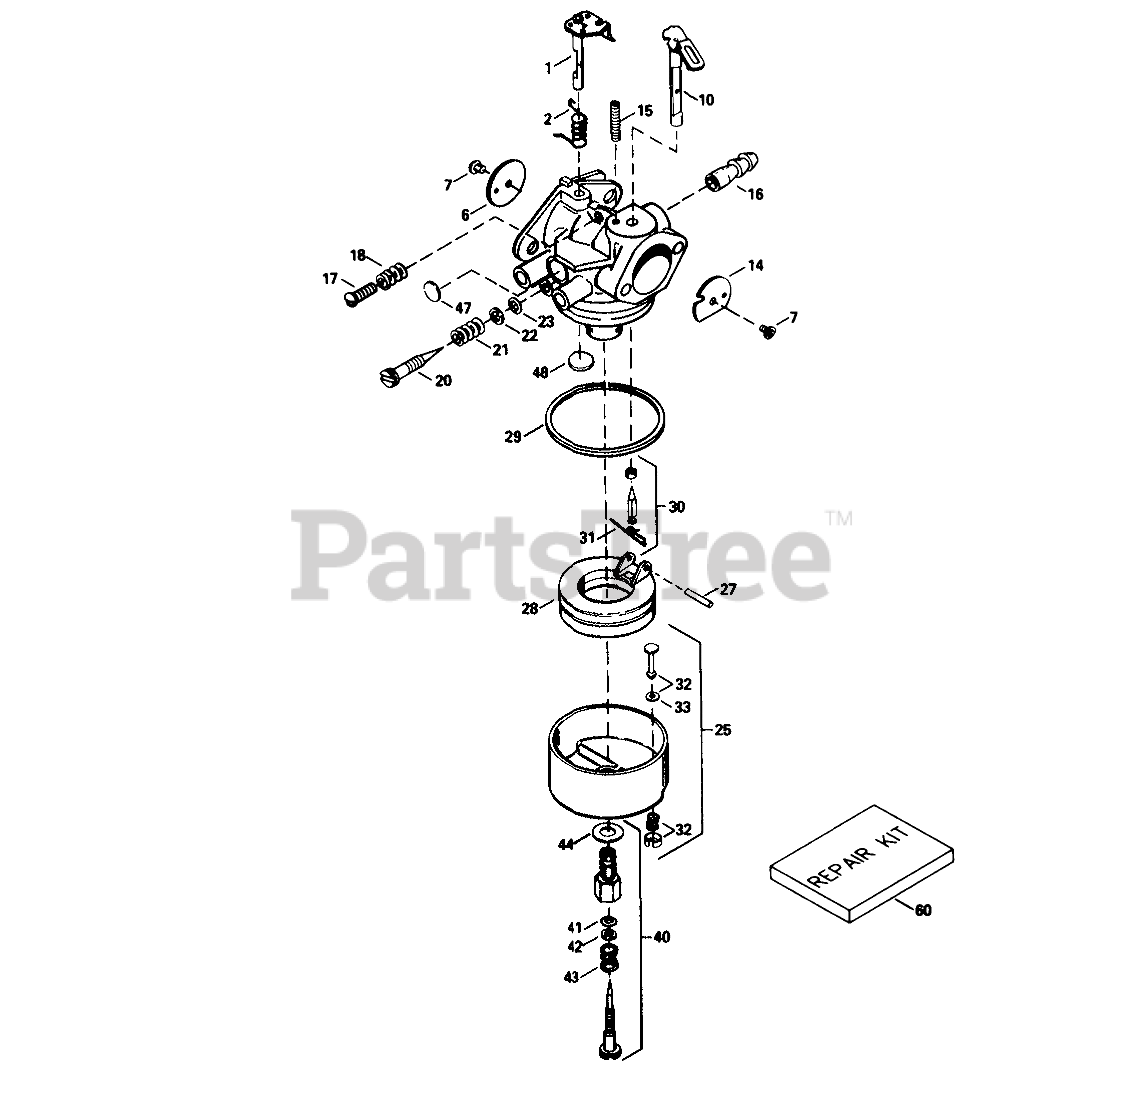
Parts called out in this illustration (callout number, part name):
1	Throttle Shaft and Lever ASM
2	Spring-Return, Throttle
6	Shutter-Throttle
7	Screw-Shutter
10	Choke Shaft and Lever ASM
14	Shutter-Choke
15	Spring-Positioning, Choke
16	Fitting-Fuel
17	Screw-Throttle Crack Screw / Idle Speed
18	Spring-Tension
20	Screw-Idle Mix
21	Spring-Tension
23	"O"Ring
25	Bowl-Float (Incl. Ref. #32, & 33)
27	Shaft-Float
28	Float
29	O Ring-Bowl, Float
30	Inlet Needle-Seat & Spring Clip (Incl. Ref. #31)
31	Clip-Spring
32	Bowl Drain Assembly (Incl. Ref. #33)
33	Gasket-Plunger, Drain
40	Mian Adj. Screw Asm.
41	"O"Ring
44	Washer-Bowl Nut
47	Plug-Welch, Idle Mixture Well
48	Plug-Welch, Atmospheric Vent
60	Kit-Repair
